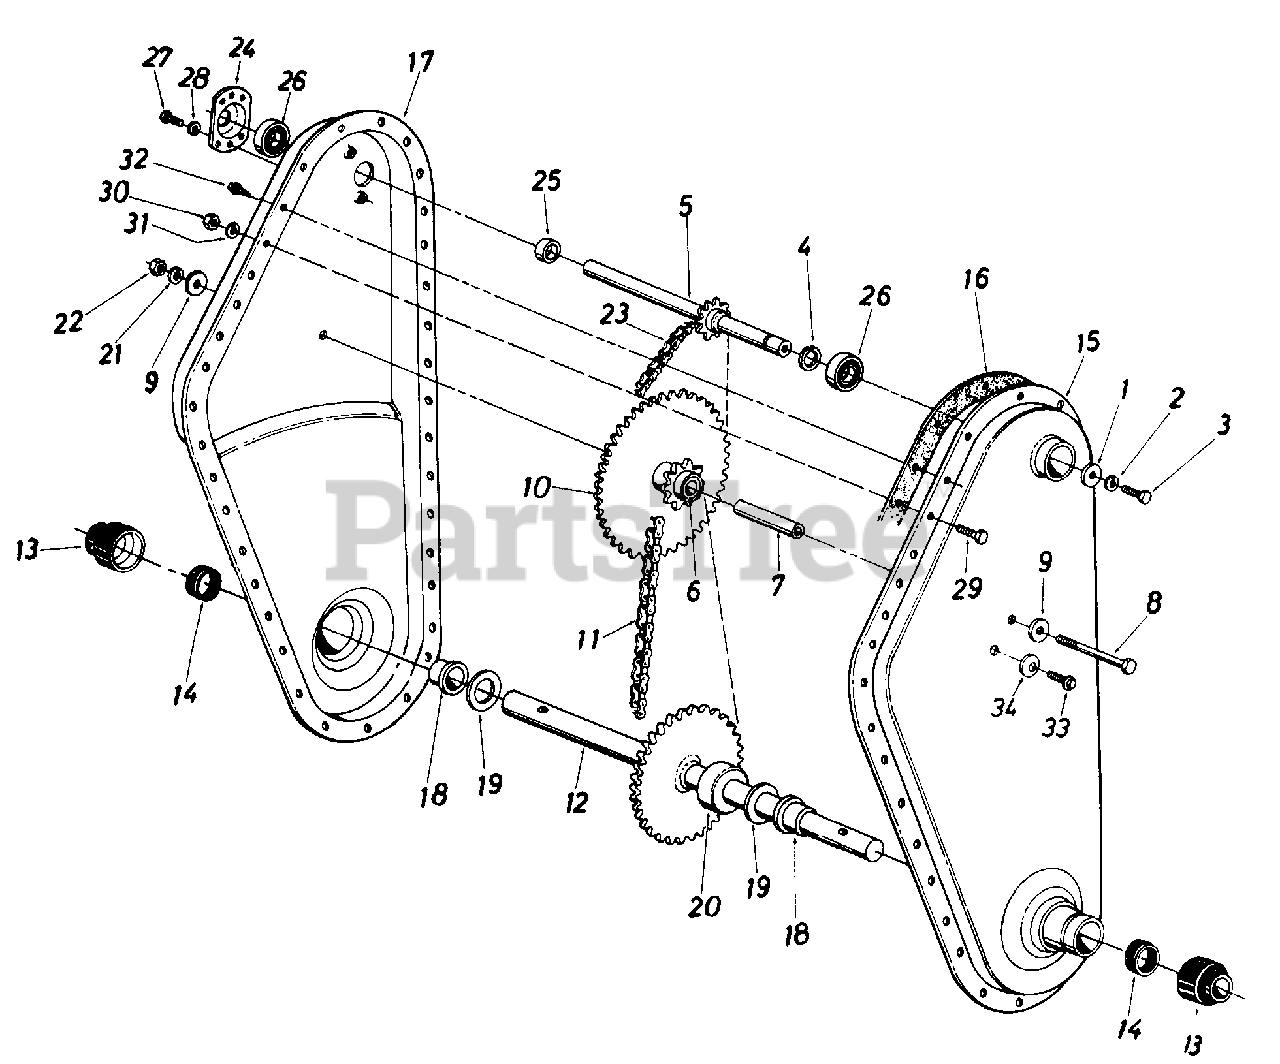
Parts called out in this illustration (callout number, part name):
1	Fl-Wash. 1/4" I.D. x .93" O.D. x .1 20
2	L-Wash. 1/4" I.D.
3	Hex Bolt 1/4-28 x .62n Lg. w/Patch
4	External Snap Ring 5/8" Dia.
5	Input Shaft Ass'y.
6	Bearing 5/8" I.D. x 3/4" O.D. x 1.860" Lg.
7	Sprocket Hub Tubing 3/8" I.D. x 5/8" O.D. x 1.90
8	Hex Bolt 3/8-24 x 2 75" Lg.
9	Fl-Wash. 3/8" I.D. x 1.25" O.D. x .10
10	Sprocket Ass'y.
11	#50 Chain 618" Pitch x 46 Links Endless
12	Tine Shaft Ass'y.
13	Dust Cup
14	Seal Ring Single Lip, Springless
19	Fl-Thrust Wash. 1.0" I.D. x .03Thk.
20	Step Spacer
21	L-Wash. 3/8" I.D.
22	Hex Nut 3/8-24 Thd.
23	#35 Chain 3/8n Pitch x 52 Links Endless
24	Bearing Housing 1.38" I.D.
25	Spacer
26	Ball Bearing .625" I.D. x 1.38n O.D. x .437
27	Hex Wash. SF-Tap Scr. 1/4-20 x .50" Lg.
28	L-Wash. 1/4" I.D.
29	Hex Bolt 5/16-18 x .75" Lg.
30	Hex Nut 5/16-18 Thd.
31	L-Wash. 5/16" I.D.
32	Hex Wash. SF-Tap Scr. 1/4-20 x.50" Lg.
33	Hex Wash. Hd. Tap Scr. 1/4-20 x .38n Lg.
34	Bell-Wash. .265" I.D. x .75" O.D.
